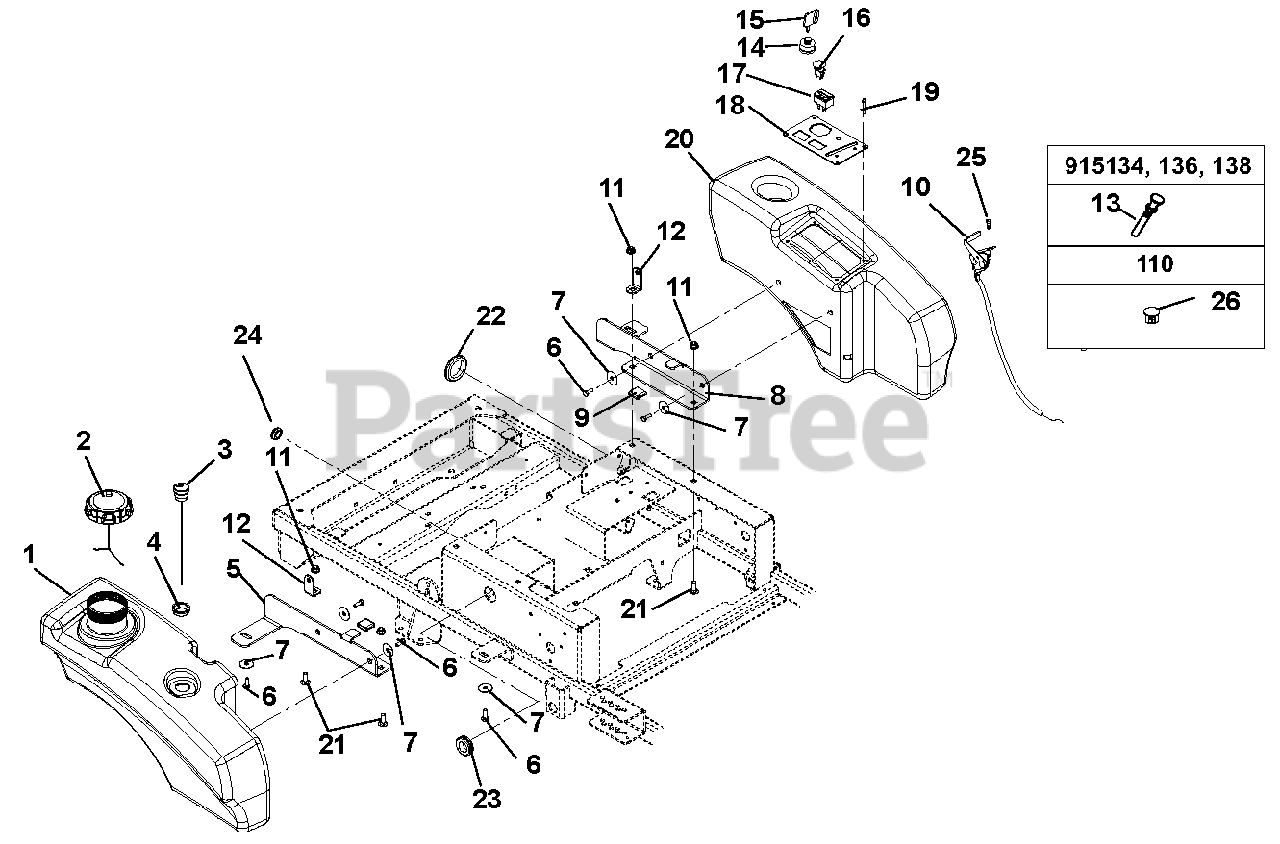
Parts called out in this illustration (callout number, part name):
1	Tank, XL
2	Fuel Cap
3	Gauge, Remote Fuel 10.0"
4	Grommet, Fuel Gage
5	Bracket, Right Hand Rear Tank Mount
6	Bolt, Serrated Hex Flange Washer Head .312-18 x .50
7	Washer, Flat-Steel .347 x 1.254 x .048
8	Bracket, Left Hand Rear Tank Mount
9	Grip, Rubber
10	Cable, Throttle (915134, 136, 138)
11	Nut, .38-16 Nyloc Flange
12	Bracket, Hood Pivot
13	Cable, Choke (915134, 136, 138)
14	Key Switch
15	Key, w/cap
16	Switch, Clutch
17	Hour Meter- Digital
18	Control Panel
19	Rivet, Plastic .195 Diameter
20	Fender, XL
21	Bolt, Round Head Square Neck .38-16 x 1.00 Grade 5
22	Grommet, 2.00"
23	Grommet .125 x 1.000 ID
24	Grommet, Rubber 5/8 ID/1.13 OD
25	Screw, Tapping 10-24 x .50 Hex Washer Head Thread
26	Hole Plug, Plastic .44 Hole (915110)
